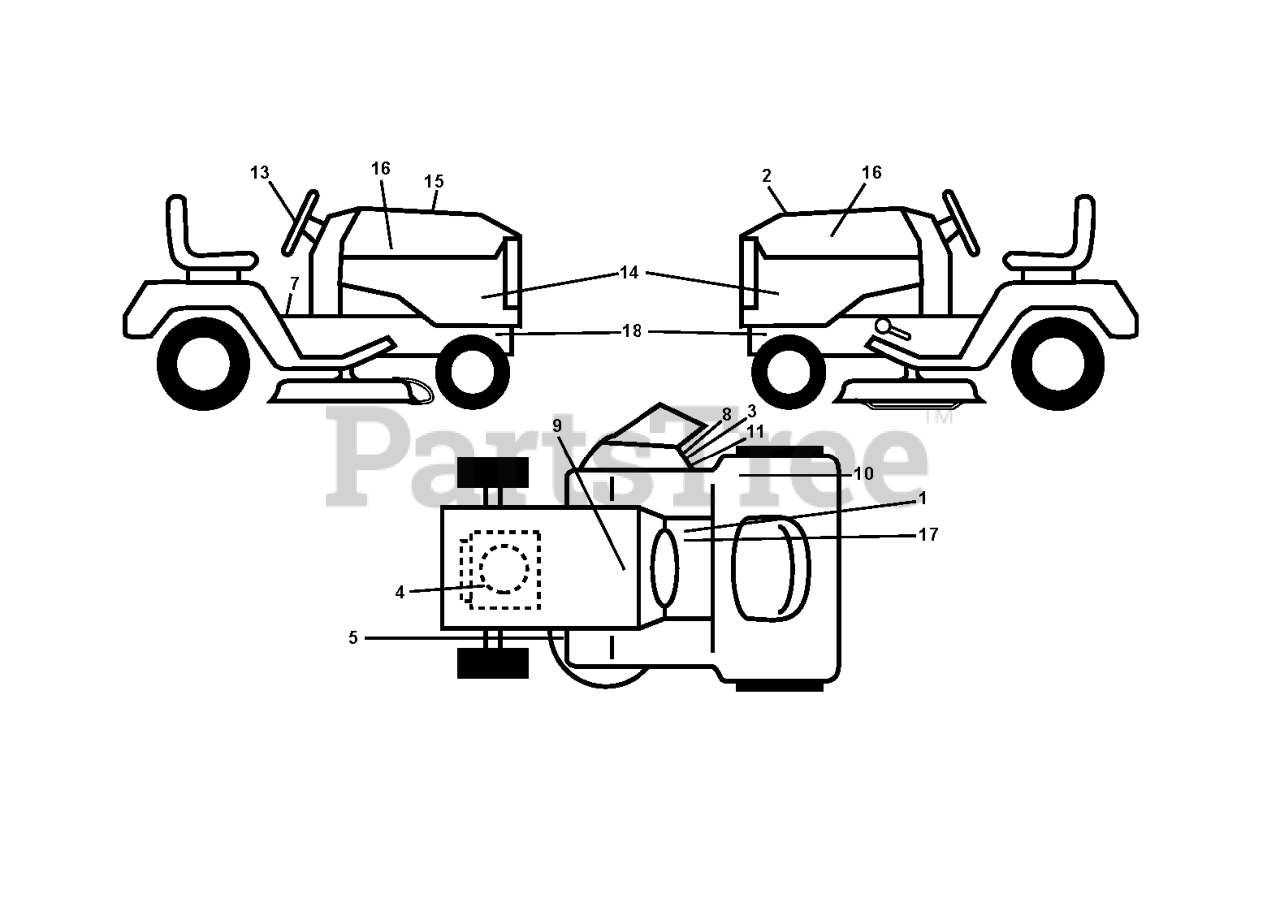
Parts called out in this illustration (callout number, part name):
1	DECAL
2	DECAL.HOOD.TOP.INSERT.
3	DECAL, DEFLECT WARNING
4	DECAL
5	DECAL
7	LABEL
8	DECAL.MOWER.SCH.48/54
9	DECAL BTRY SYMBOLS
10	DECAL.FENDER
11	DECAL.INTERNATIONL.CUTFINGER
13	DECAL.WHEEL.STRG.LGN.H
16	DECAL.HOOD.NAMELOGO.HUSQ
17	DECAL PARK BRAKE
